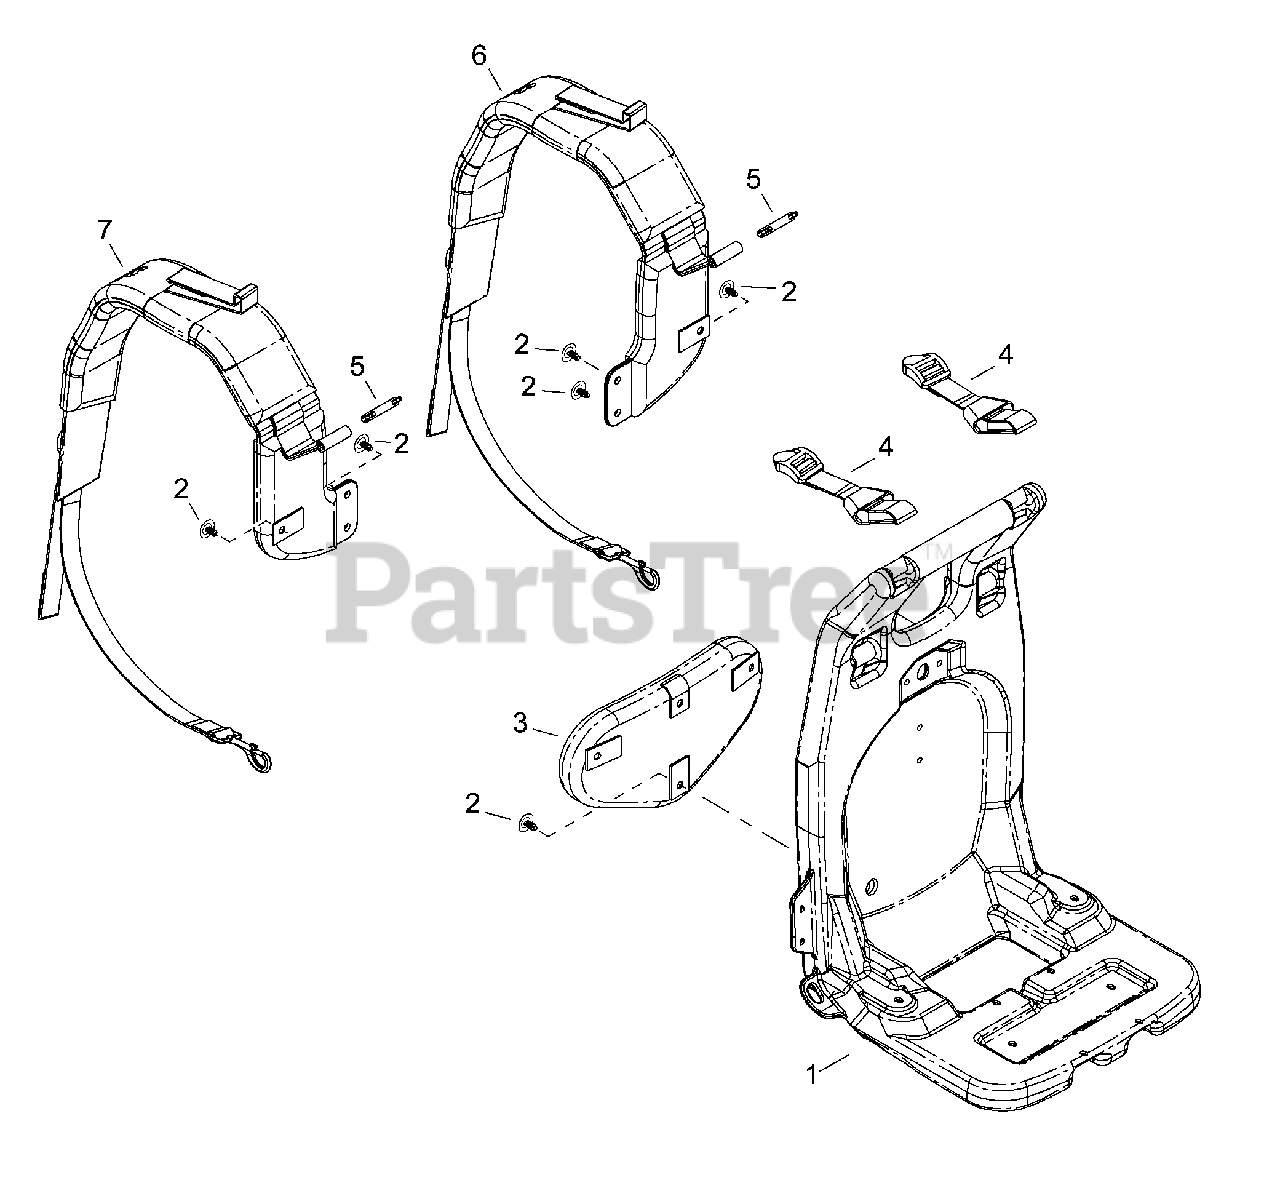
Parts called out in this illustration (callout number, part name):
1	FRAME, BACKPACK
2	CLIP
3	PAD, BACKPACK
4	STRAP, HARNESS
5	CLIP, HARNESS
6	HARNESS ASSY, RIGHT
7	HARNESS ASSY, LEFT
